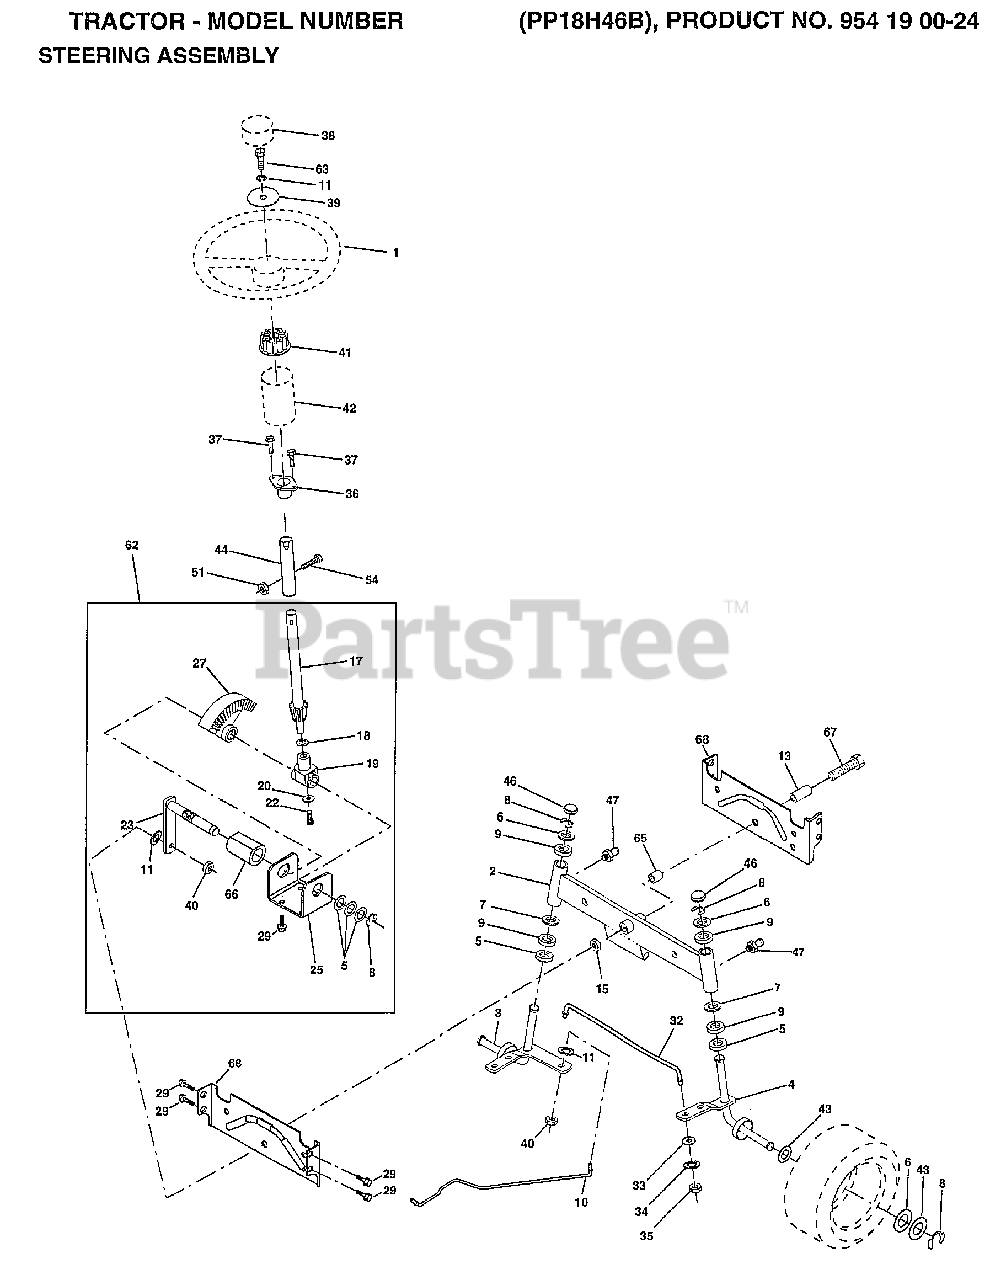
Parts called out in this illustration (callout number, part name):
2	AXLE ASM
3	SPINDLE.ASM.LH
4	"SPINDLE ASM,RH"
5	WASHER .T
6	WASHER
7	WASHER
8	RING
9	COL. SRTG. BEAR.
10	DRAGLINK-STAMPED
11	LOCKWASHER
13	BEARING AXLE
15	"NUT-LOC,FLANGE LT"
17	SHAFT ASM STEERIN
18	THRUST WASHER
19	SUPPORT SHAFT
20	WASHER SHIM 1/4 X 5/8 X 062
22	SCREW HEX SOC1/4-
25	BRKT-STEERING
27	GEAR SECTOR
29	SCREW
32	ROD.TIE.19.75
33	WASHER M
34	LOCKWASHER
35	NUT.LOCK.5/16-24
36	BUSHING.STEERING
37	"SCREW-TT,10-32 FL"
38	"INSERT,STR WHEEL"
39	WASHER T
40	GRIPCO NUT
41	ADAPTER LT
42	BOOT.STEER.PL
43	WASHER
44	EXT SHAFT STEERIN
46	CAP
47	ZERK M
51	NUT
54	BOLT
62	KIT STEERING ASM
63	BOLT
65	SPACER AXLE
66	"BEARING-ARM,PITMA"
67	BOLT
68	BRACE AXLE
